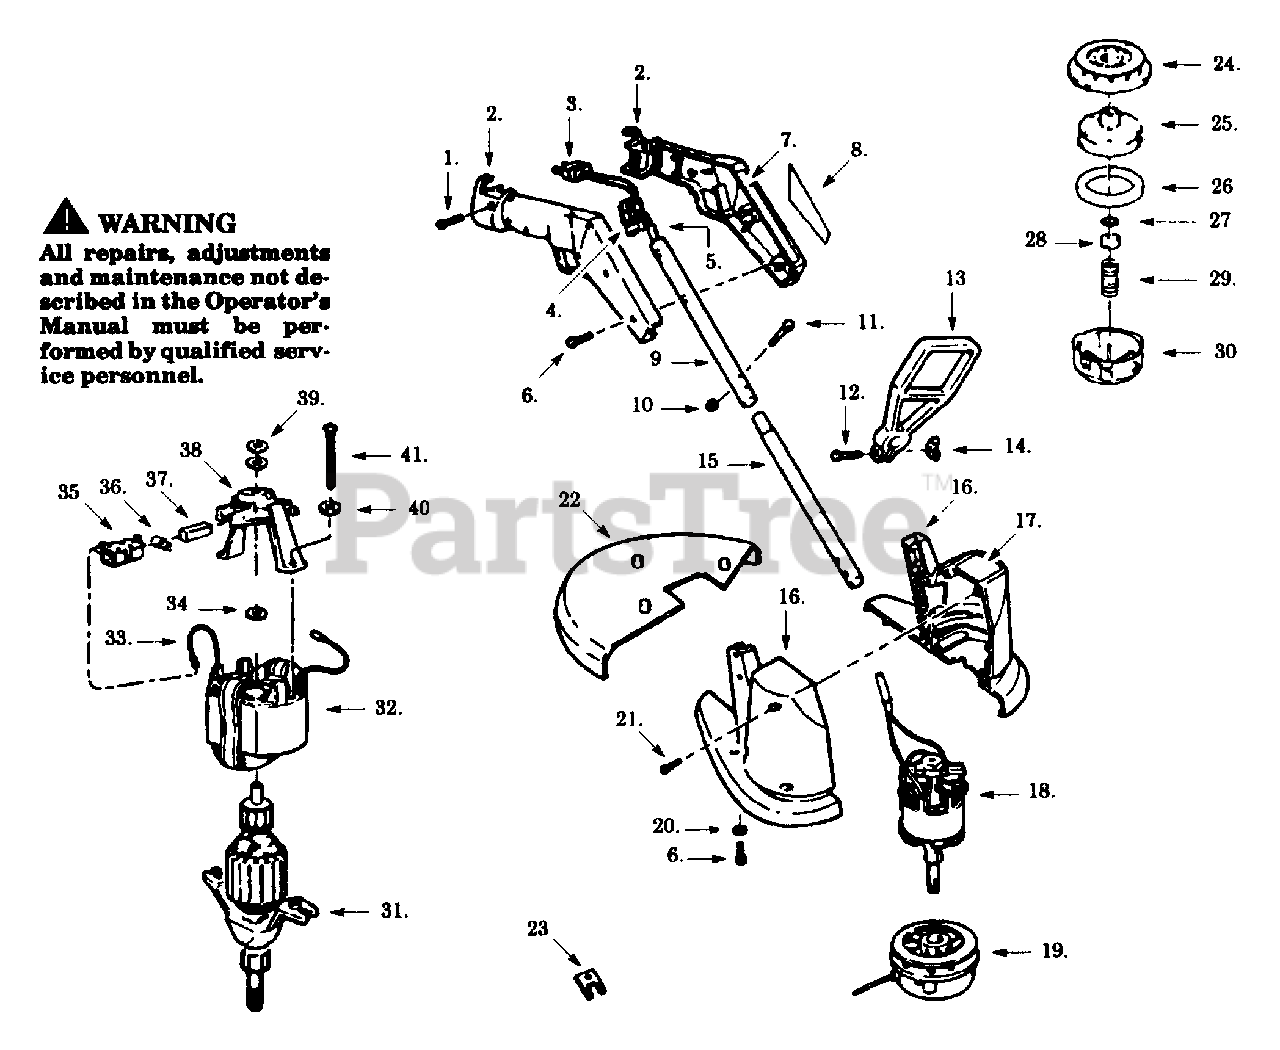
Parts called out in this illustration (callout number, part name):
2	Handle Set
3	Power Plug
4	Trigger Switch
5	Harness Ass'y.
7	Handle Label
8	Warning Label (Not a serviceable part)
9	Upper Tube
10	Stop Nut
13	Assist Handle
14	Wing Nut
15	Lower Tube
16	Housing Set
17	Housing Top Label
18	Motor Ass'y.
19	Cutting Head Ass'y.
22	Guard & Blade Ass'y.
24	Rear Plate/Baffle Ass'y.
25	Spool & Line
26	Foam Pad
28	Adapter Nut
30	Hub Ass'y.
31	Armature Endbell
32	Field Ass'y.
33	Lead Wire Ass'y.
35	Brush Holder Ass'y.
36	Brush Spring
38	Endbell Ass'y. (Brush)
39	Retaining Ring
40	Lockwasher
